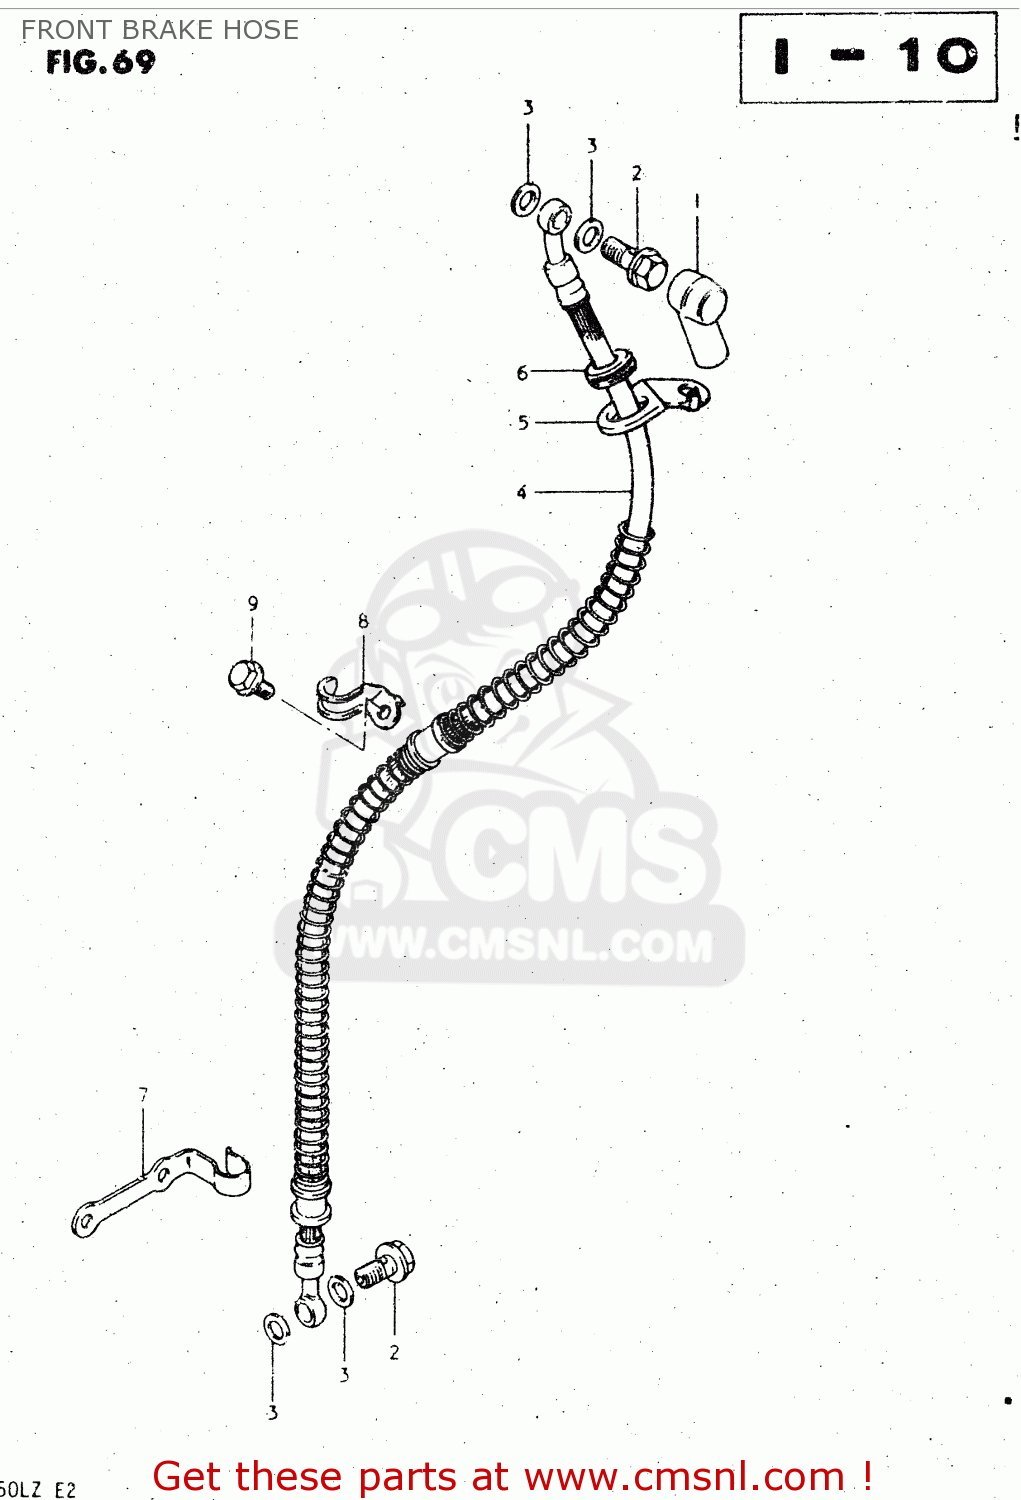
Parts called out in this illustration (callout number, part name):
1	BOOT,MASTER CYLINDER
2	BOLT,UNION
3	WASHER
4	HOSE,FRONT BRAKE
5	GUIDE,BRAKE HOSE
6	GROMMET
7	GUIDE,BRAKE HOSE NO.2
8	GUIDE,BRAKE HOSE NO.3
9	BOLT
